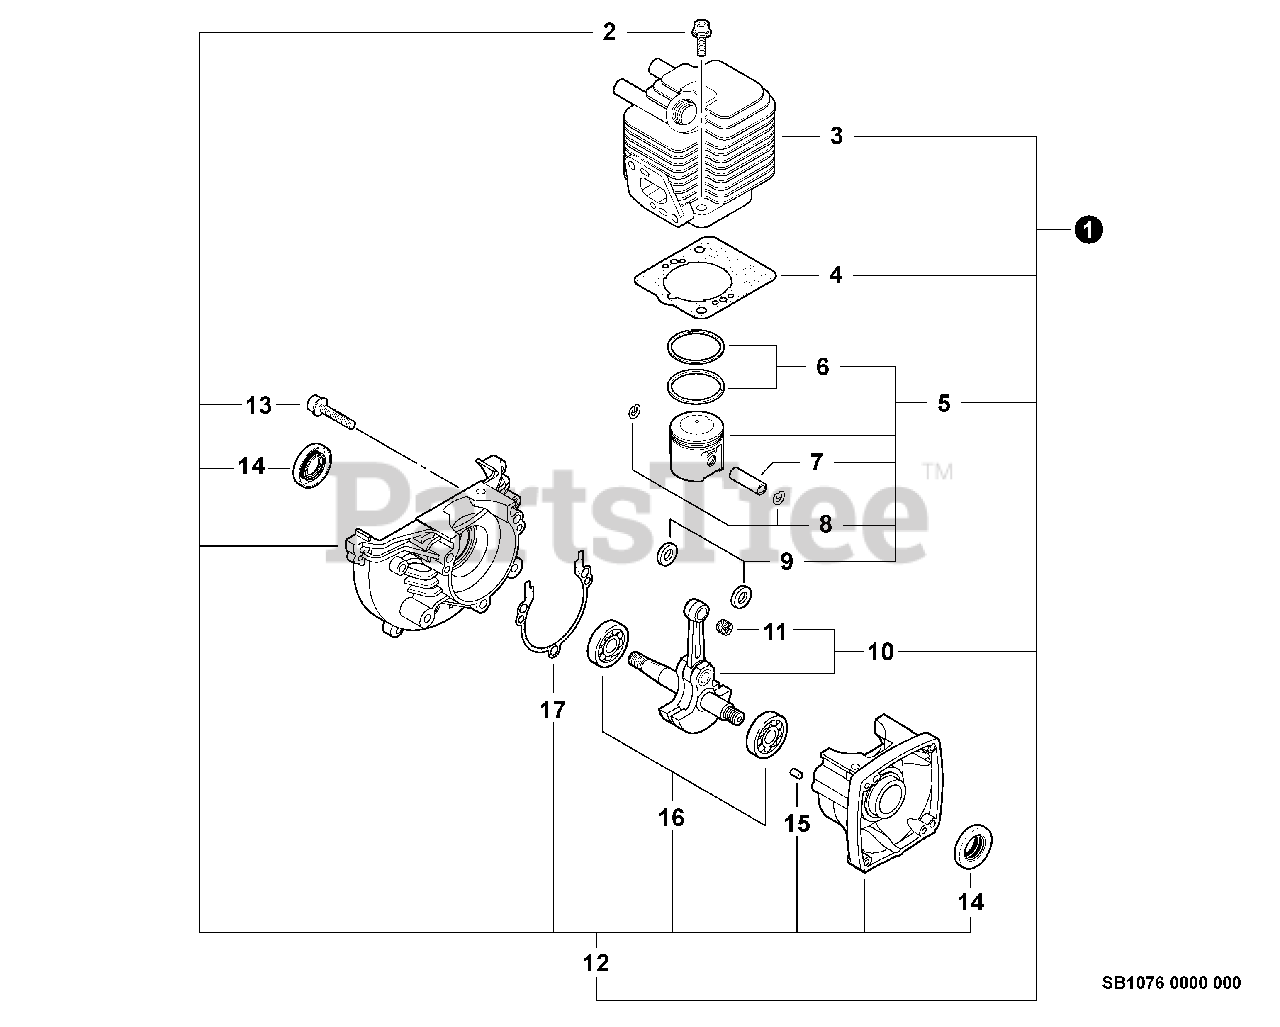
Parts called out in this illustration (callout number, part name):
1	SHORT BLOCK
2	BOLT 5×22
3	CYLINDER
4	GASKET, CYLINDER
5	PISTON KIT
6	RING, PISTON
7	PIN, PISTON 8
8	RING, SNAP
9	WASHER, THRUST
10	CRANKSHAFT ASSY
11	BEARING, NEEDLE
12	CRANKCASE KIT
13	BOLT 5×28
14	SEAL, OIL 12
15	PIN, LOCATING 4
16	BEARING, BALL - 6201 C3
17	GASKET, CRANKCASE
